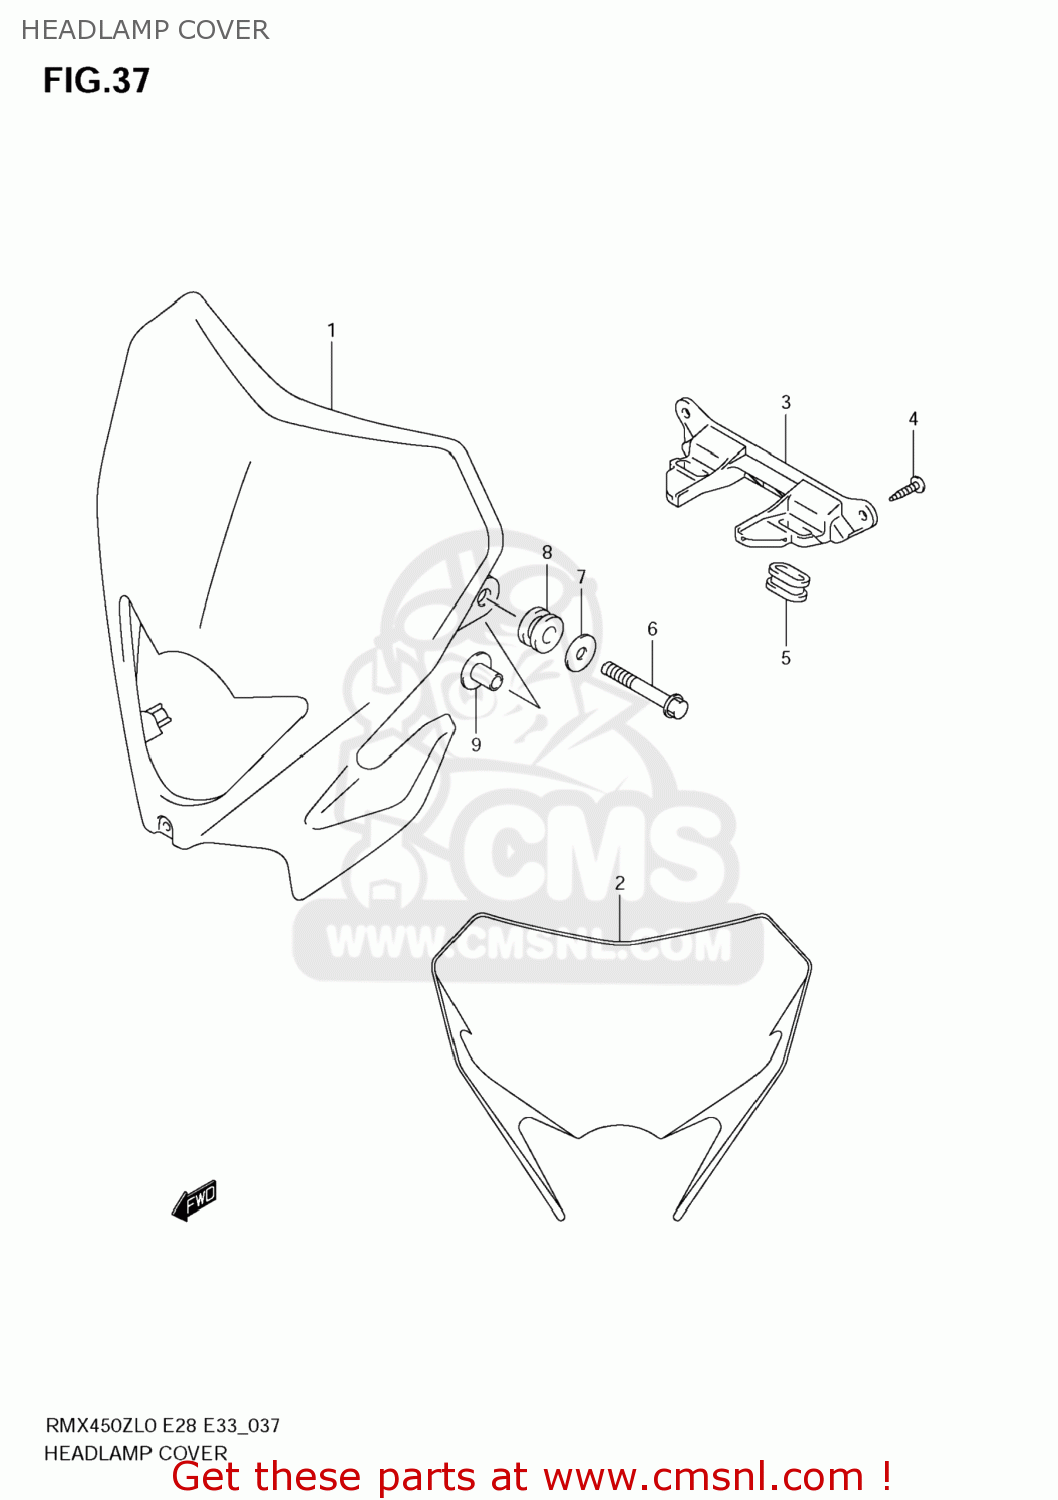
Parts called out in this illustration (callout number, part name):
1	COVER,HEADLAMP
2	TAPE,HEADLAMP COVER
3	COVER,HEADLAMP LWR
4	SCREW
5	CUSHION,HEADLAMP COVER
6	BOLT(6X25)
7	WASHER(6.5X18X1.6)
8	CUSHION
9	WASHER
